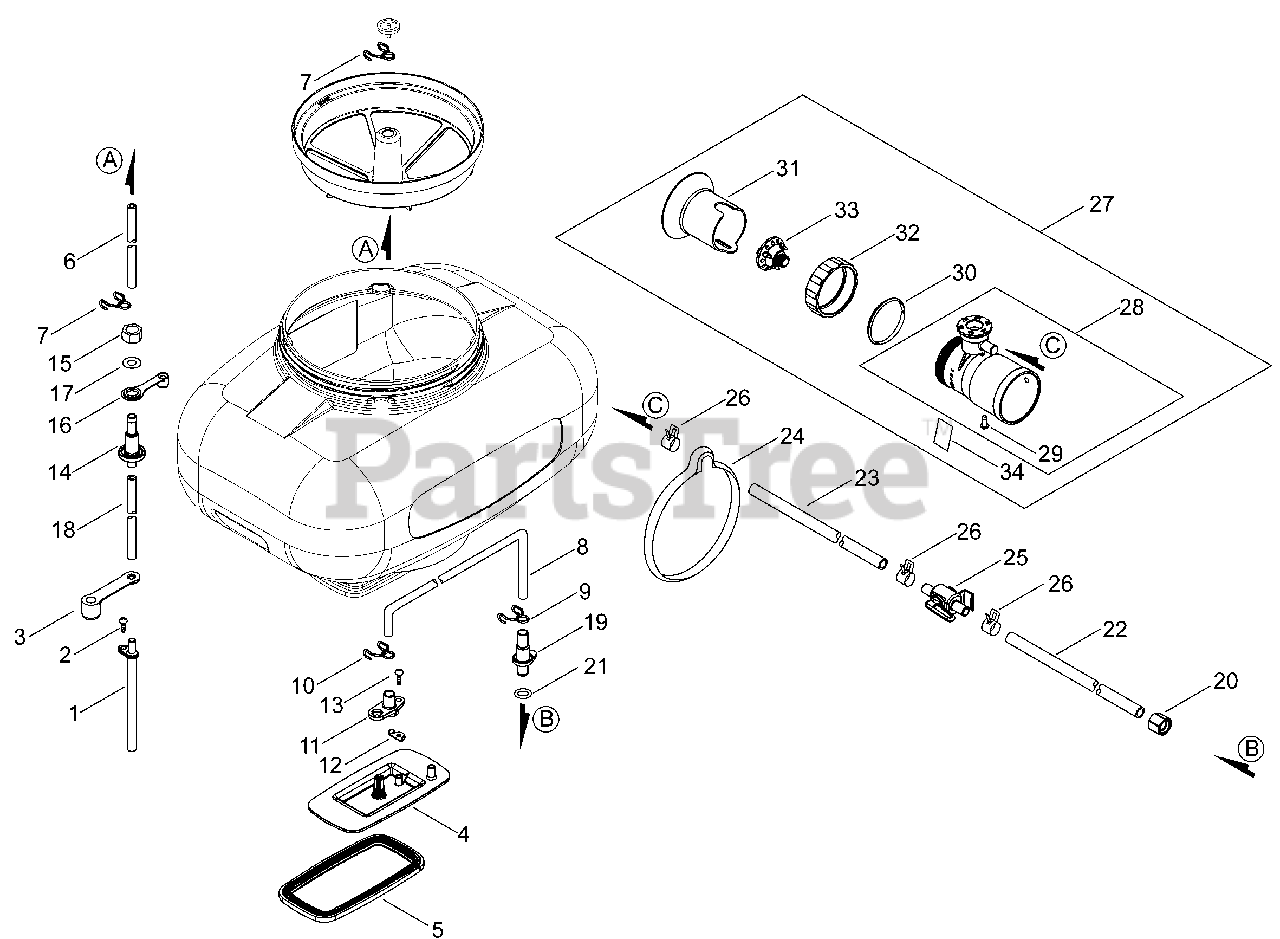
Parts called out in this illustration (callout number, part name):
1	PIPE, VENT
2	SCREW 5×16 SUS
4	PLATE, BOTTOM
5	GASKET, PLATE
6	PIPE, INNER PRESSURE 7×11×500BL
8	PIPE, DISCHARGE
11	NIPPLE, HOSE
12	PLATE, EYE
13	SCREW, TAPPING
14	CONNECTOR, PIPE
17	WASHER 12
18	PIPE, OUTER PRESSURE 7×11×170L
19	CONNECTOR, PIPE
21	O-RING 3×13
22	PIPE, DISCHARGE 9×13×720L
23	PIPE
24	CLIP, TUBE Ø55
25	VALVE
28	+NOZZLE
29	++SCREW 5×12
30	+RING, NOZZLE
31	+COLLAR, NOZZLE
33	+NOZZLE
34	+LABEL, MIST
